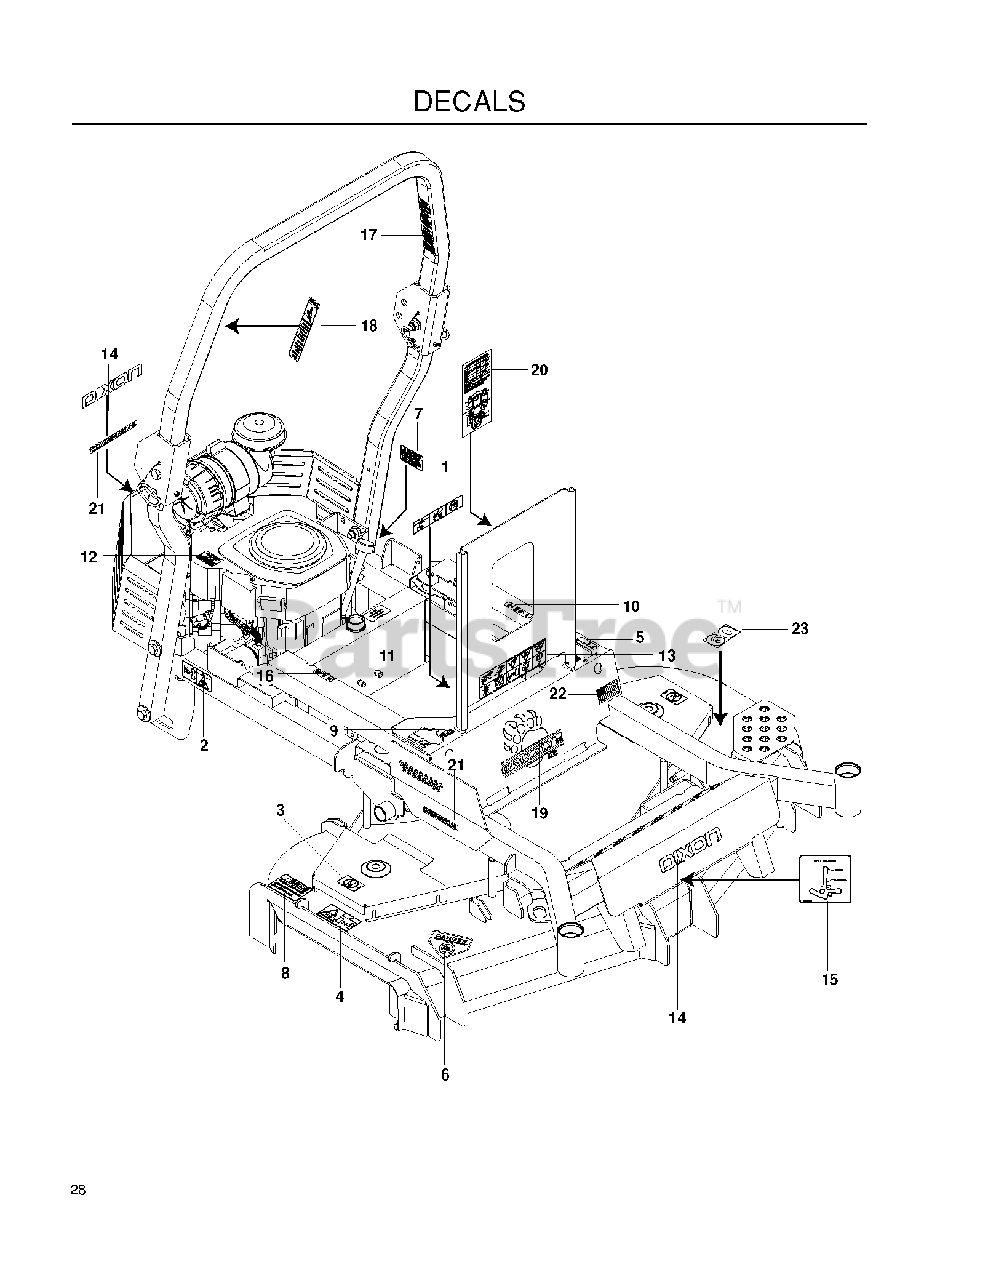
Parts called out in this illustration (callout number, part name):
1	DECAL, BATTERY
2	DECAL, BELT DRIVE
3	DECAL, NO STEP
4	DECAL, EURO SEVERING
5	DECAL, MOTION CONTROL
6	DECAL, CPSC
7	DECAL, PROP. 65
8	DECAL, CAUTION
9	DECAL, F.S.T.
10	DECAL, PARK BRAKE
11	DECAL, OIL TANK
12	DECAL, EXHAUST
13	DECAL, WARNING
14	DECAL, DIXON LOGO FLAT
15	DECAL, BELT ROUTING
16	Fuse Decal
17	DECAL, ROPS
18	DECAL, ROPS, WARNING
19	DECAL GRIZZLY SE
20	DECAL, SERVICE
21	DECAL, COMMERCIAL
22	DECAL, FLAG
23	DECAL, 60"
23	DECAL, 72"
